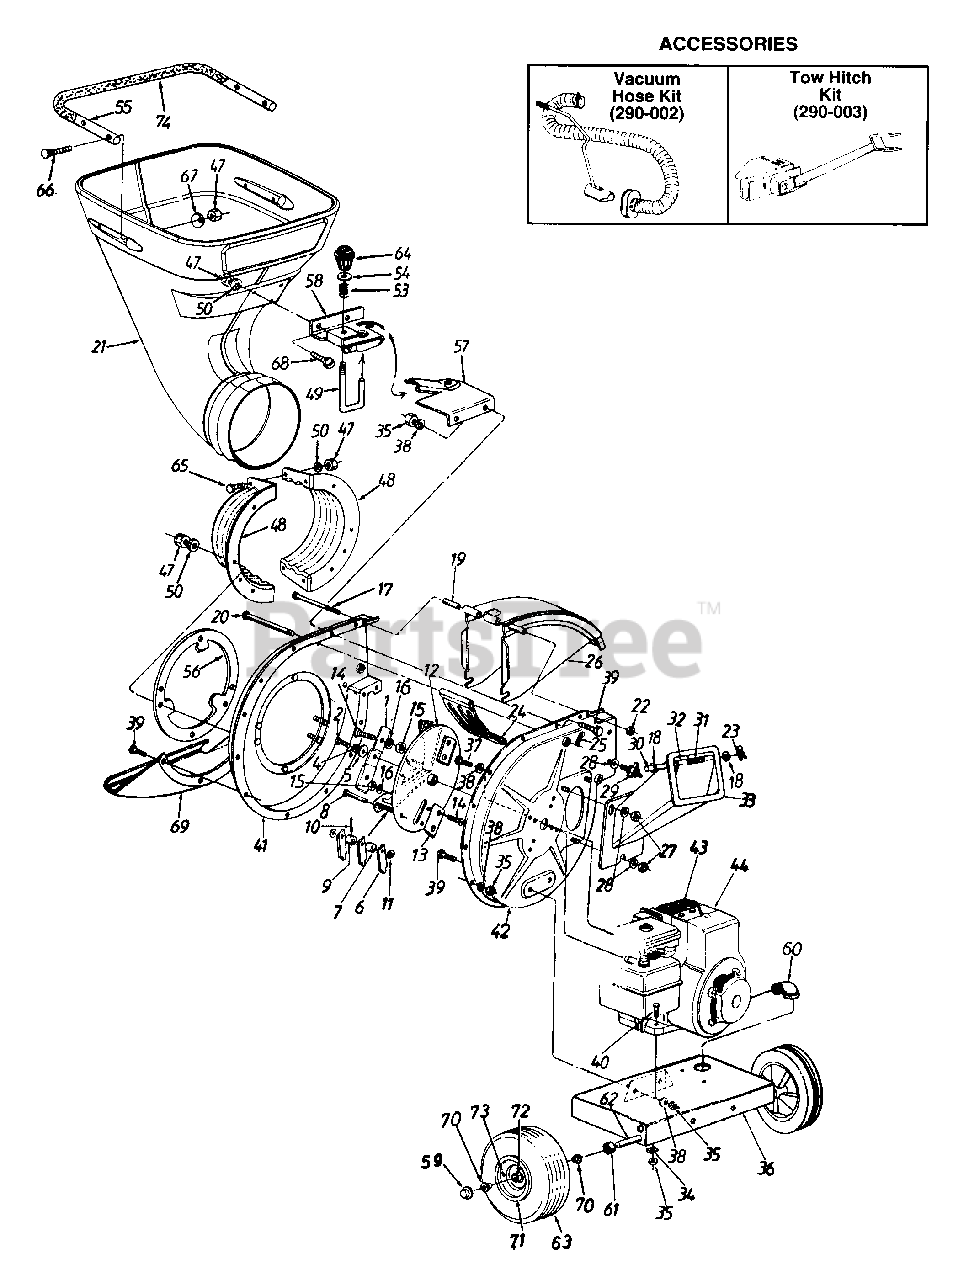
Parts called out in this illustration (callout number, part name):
1	Blade
2	Hex Patch Bolt 3/8-24 x 2.25" Lg.
4	L-Wash. 3/8" I.D. H.D.
5	Fl-Wash. .406" I.D. x 1.25" O.D. Hdn.
6	Flail
7	Flail Spacer
8	Clevis Pin .496" Dia.
9	Flail Spacer w/.160" Dia. Hole
10	Spring Roll Pin 1.12" Lg.
11	Fl-Wash. .531" I.D. x .94" O.D.
12	Impeller Ass'y. Comp.
13	Chipper Blade
14	Flat Hd. Scr. 5/16-24 x .75" Lg.
15	Hex Top L-Nut 5/16-24 (Gr. 5)
16	L-Wash. 5/16" I.D.
17	Hex Bolt 1/4-20 x 3.75" Lg.
18	Fl-Wash. .281" I.D. x .50" O.D.
19	Chute Hinge Spacer 1.66" Lg.
20	Clevis Pin .5" Dia. x 4.62" Lg.
21	Rotating Hopper
22	Hex Ctr. L-Nut 1/4-20 Thd.
23	Cotter Pin
24	Shredder Screen
25	Internal Cotter Pin 3/8" Dia.
27	Hex Nut 5/16-18 Thd. (Gr. 5)
28	Bell-Wash. .345" I.D. x .88"
29	Hand Knob
30	Chipper Door Rod
31	Torsion Spring 1.14" Lg.
35	Hex Nut 5/16-18 Thd. (Gr. 5)
37	Hex Bolt 5/16-24 x .75" Lg.
38	L-Wash. 5/16" I.D.
39	Hex Bolt 5/16-18 x .75" Lg. (Gr. 5)
40	Hex Bolt 5/16-18 x 1.5" Lg.
44	Engine
47	Elastic Lock Nut 5/16-18 Thd.
48	Hopper Mtg. Collar
49	Locking Pin
50	Fl-Wash. 5/16" I.D.
53	Spring 1.5" Lg.
54	Fl-Wash. .385" I.D. x .62" O.D.
60	Drain Elbow
61	Spacer .64" I.D. x .38" Lg.
62	Shredder Axle
63	Wheel Ass'y. Comp.
63	Tire Only
65	Hex Bolt 5/16-18 x 1" Lg. (Gr. 5)
66	Curved Carr. Bolt 5/16-18 x 1.25" Lg.
67	Saddle Wash..32" I.D.
68	Carr. Bolt 5/16-18 x .75" Lg.
70	Flange Bearing .632" I.D.
73	Air Valve
74	Foam Grip
